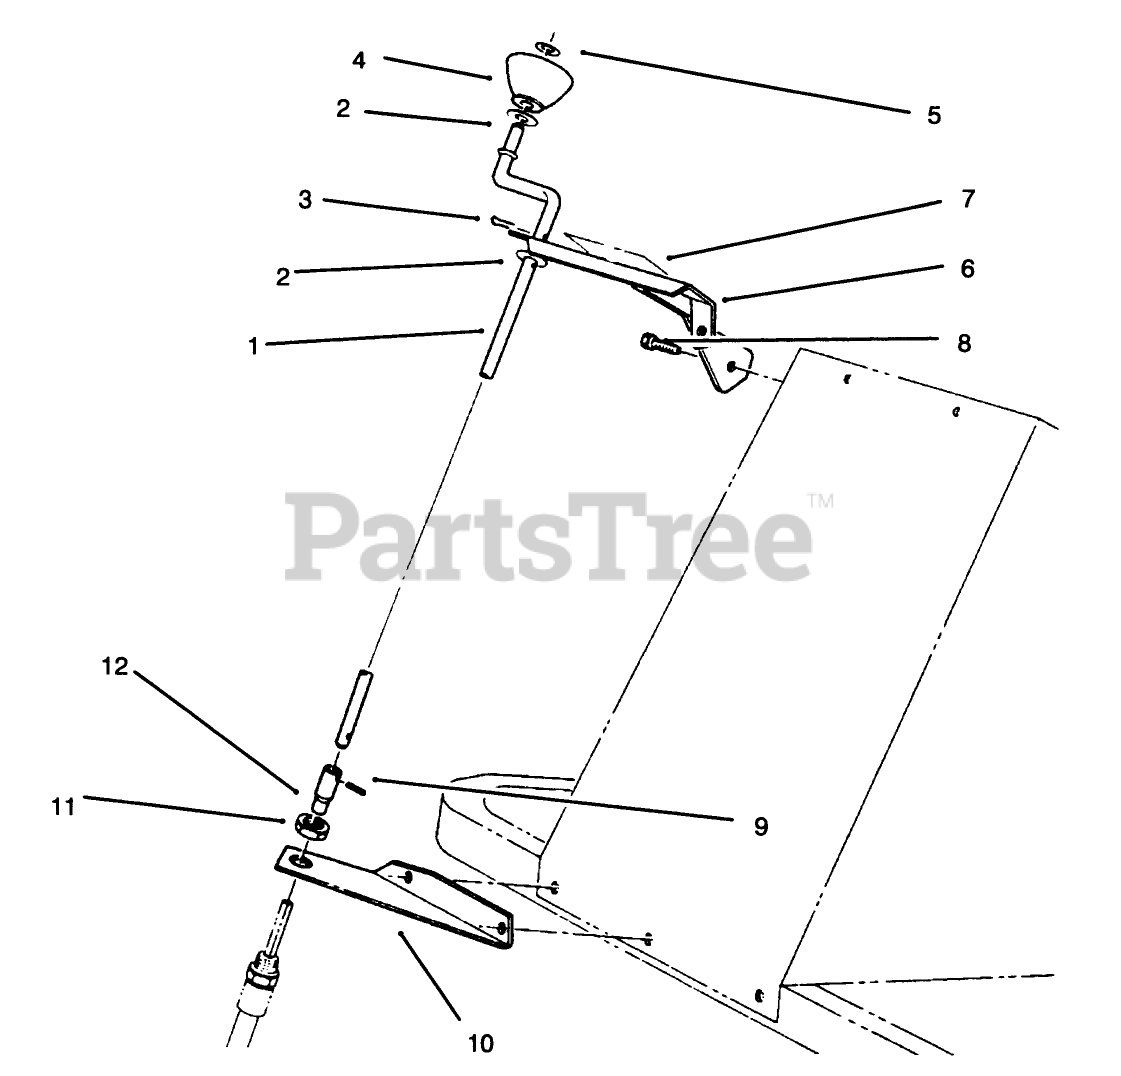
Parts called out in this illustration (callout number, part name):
1	CHUTE CONTROL ROD
2	WASHER-FLAT
3	PIN-COTTER
4	KNOB-CHUTE
5	NUT-PUSH
6	TOP BRKT R
7	DECAL-CHUTE DIRECTION
8	SCREW-HH
9	PIN-SPRING
10	BOTTOM BRKT R
11	LOCKNUT
12	COUPLER
